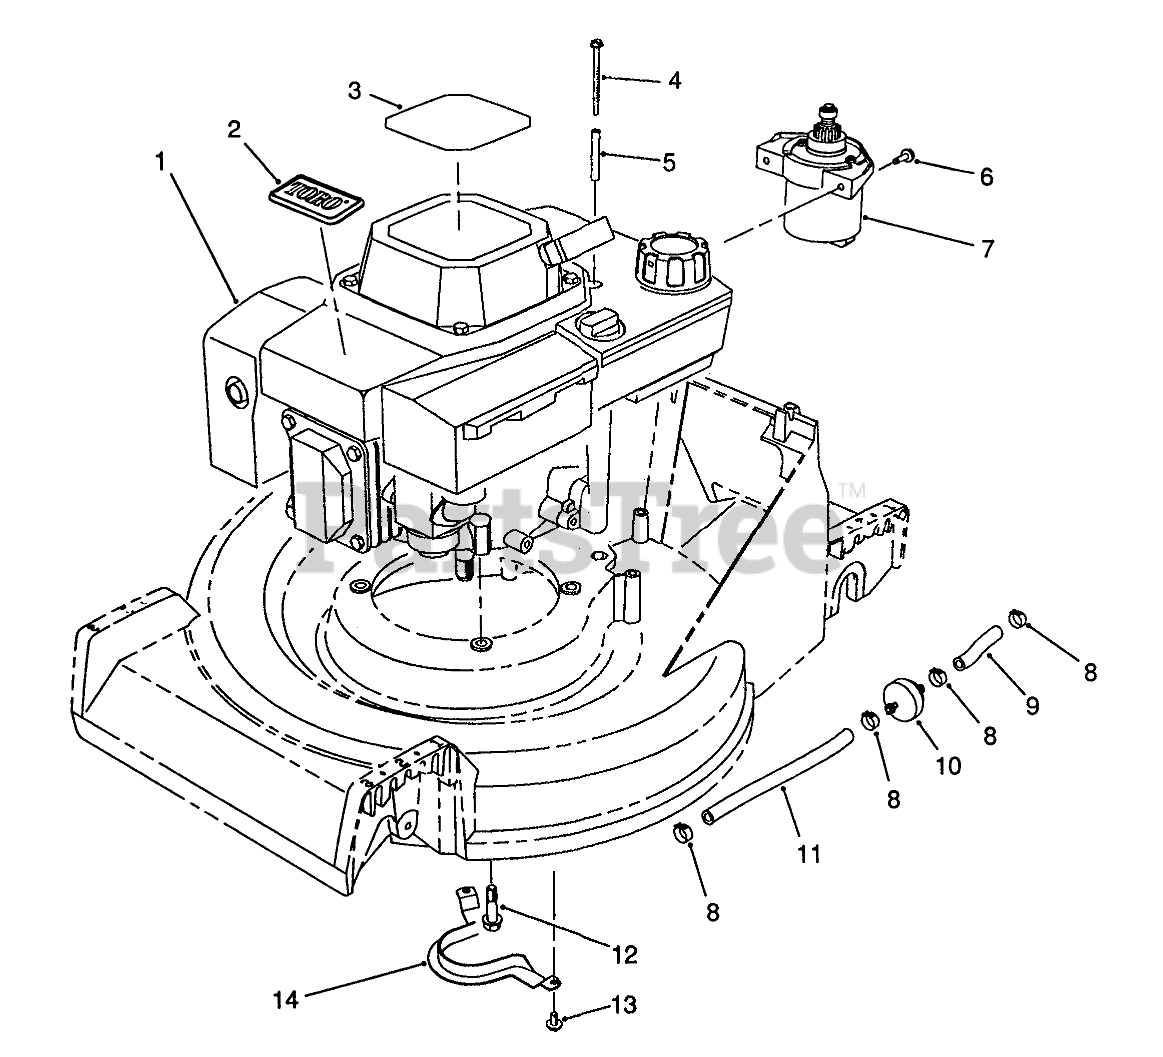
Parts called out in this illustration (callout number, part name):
1	ENGINE ASSY OHV BBC/K
2	TORO LOGO PLT
3	DECAL - OHV RECOIL
4	THRD FORMING SCREW
5	TUBULAR SPACER
6	SCREW
7	STARTER MOTOR ASM
8	CLAMP-FUEL LINE
9	LINE-GAS
10	FILTER-FUEL
11	HOSE-FUEL
12	SCREW-HWHTF
13	SCREW-HWHTF
14	Guide-Belt
